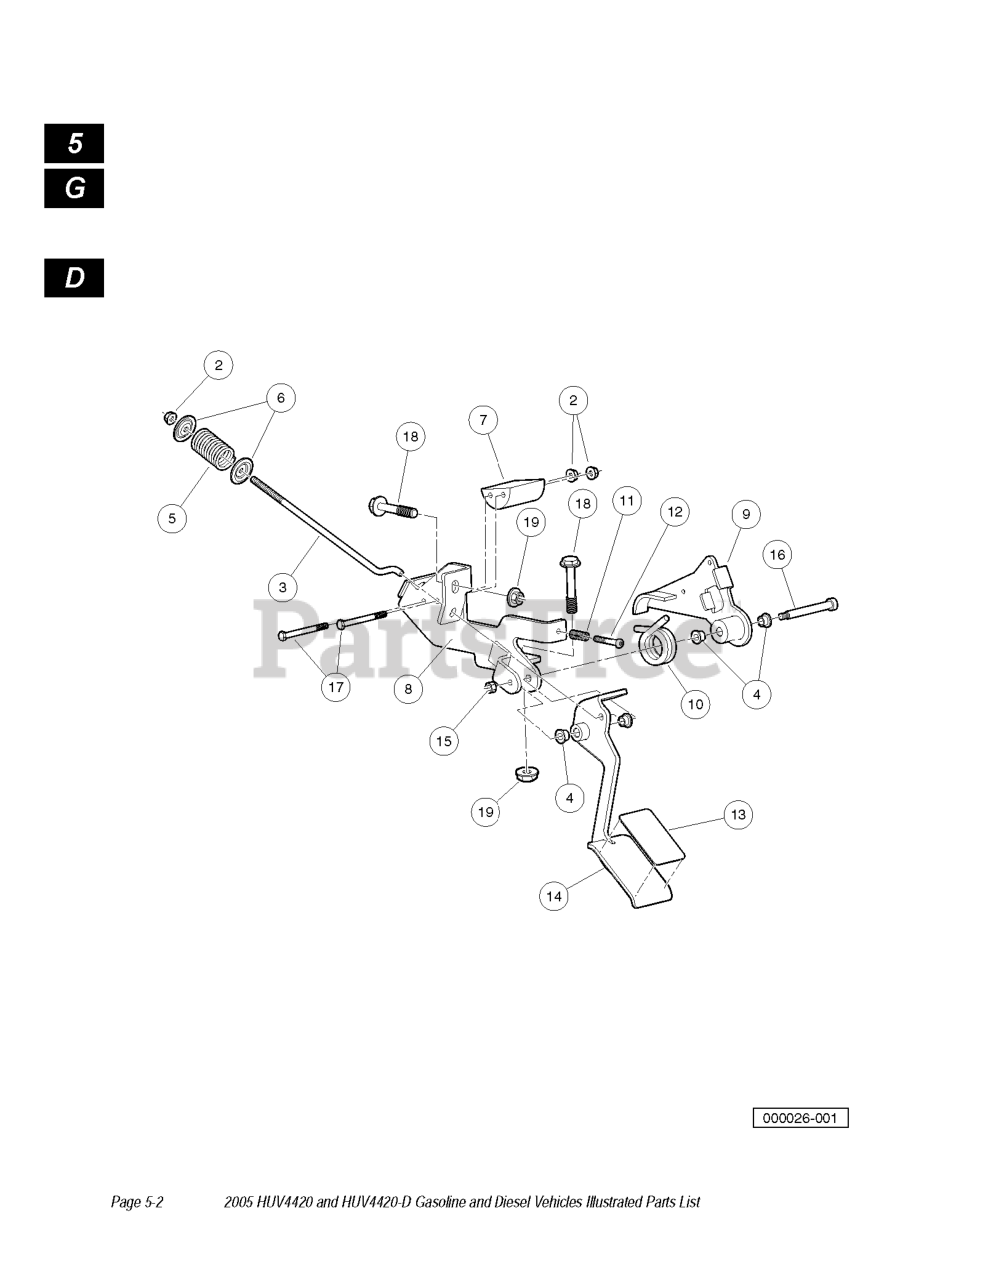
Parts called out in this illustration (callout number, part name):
1	ASM, PEDAL ACCELERATOR
2	NUT-M6X1.0 FLNG ALL MTL LOCK
4	BUSHING, GREASELESS
13	PAD, GRIP TAPE, ACCELERATOR
15	NUT M6X1 MECH DEF CENTER
16	BOLT, SHOULDER, M8 X 70, HC
17	BOLT, M6 X 1 X 70
18	BOLT FLG, M8X1.25X65
19	LOCK NUT, FLG M8 X 1.25 NYLON
